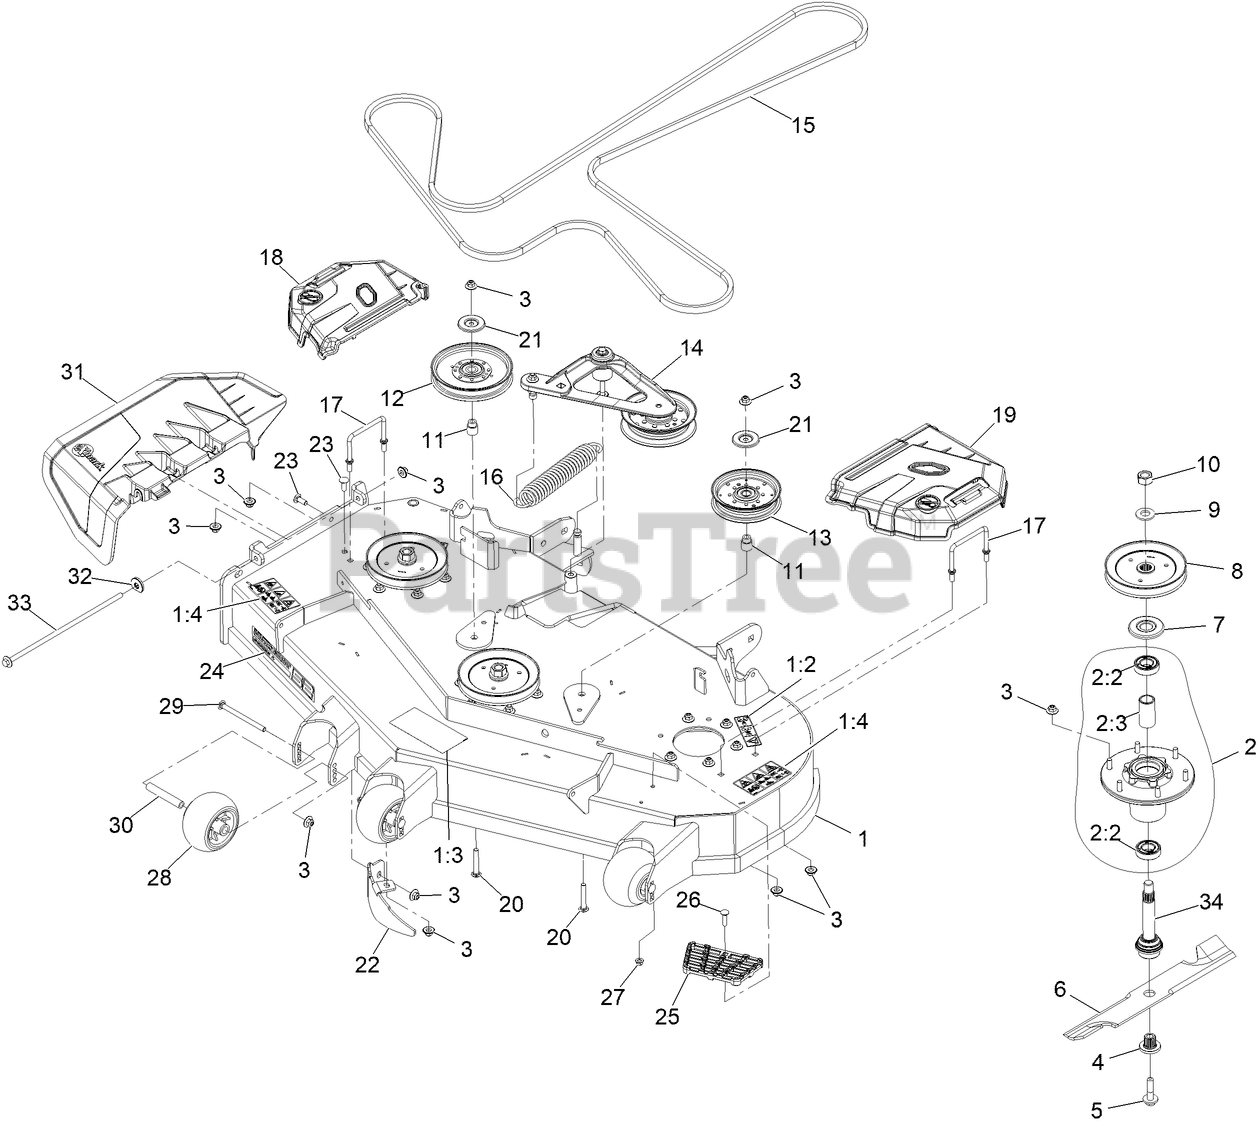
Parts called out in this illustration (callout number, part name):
1	ASM, Deck W/Decals 52
1:2	DECAL-COVER, MISSING
1:3	DECAL-ANTI-SCALP-BELT ROUTING
1:4	DECAL-DANGER THROWN OBJECTS
2	ASM-CUTTER HSG WITH BEARINGS
2:2	BEARING-BALL
2:3	SPACER-BEARING
3	Nut-Nyloc 3/8-16 Flg
4	BUSHING,SPLINED
5	SCREW,SEMS 1/2-20 X 2.19
7	GUARD,BEARING TOP .989
8	SHEAVE,BLADE DRIVE 6.50
10	NUT-HEX
11	BUSHING-IDLER
12	IDLER-PULLEY
13	PULLEY-IDLER, FLAT
14	DECK IDLER ASM
16	SPRING-EXTENSION
17	WIREFORM-COVER
18	SHIELD, RT
19	SHIELD, LT
20	SCREW-CARR
21	SHIELD-DUST
22	BAFFLE-DOGLEG, LZ-VT52
23	SCREW-CARR
24	DECAL, 524
25	STEP-DECK
26	Bolt-Carriage 5/16-18 X 1 1/4
27	NUT-HF, NI
28	ROLLER-SCALP, ANTI
29	BOLT-CARR
30	SPACER-AXLE
31	Chute-Deck Discharge
32	Retainer, Chute
33	Pin, Chute
34	ASM-SPINDLE AND SEAL
